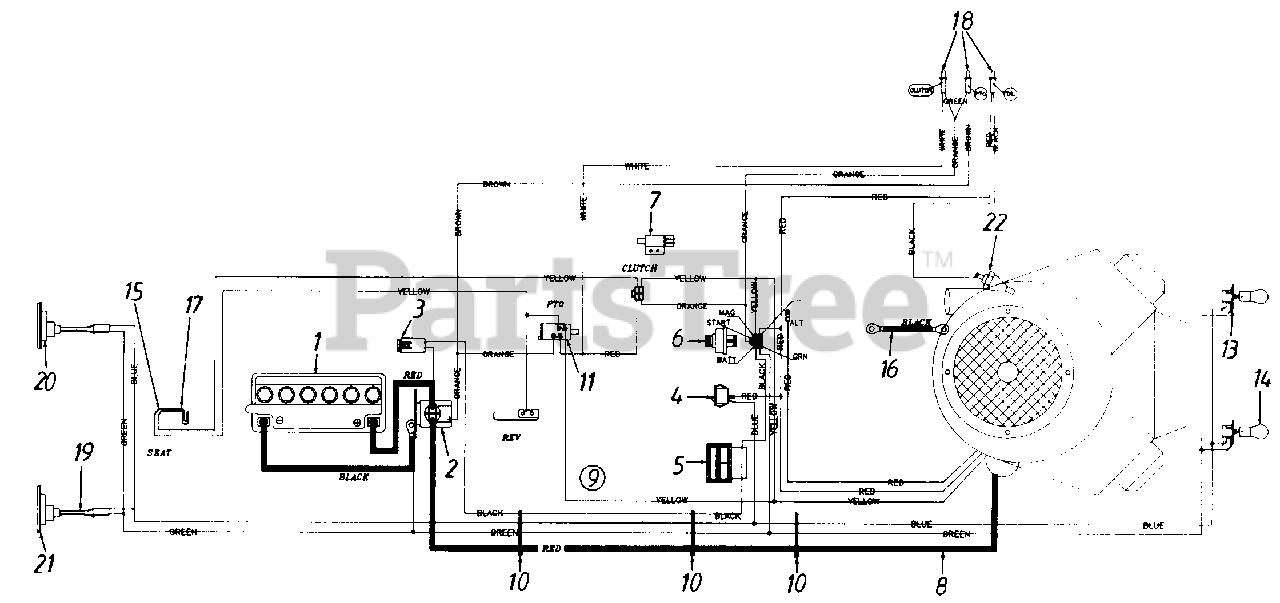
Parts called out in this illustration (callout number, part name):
1	Battery
2	Solenoid
3	Fuse 7.5 Amps
4	Light Switch
5	Ammeter
6	Ignition Switch
7	Safety Switch (Clutch)
8	Electric Wire 30" Lg.
9	Wire Harness
11	Safety Switch (Deck)
13	Socket
14	Bulb (Headlight)
15	Safety Switch (Seat)
16	Ground Wire 7.5" Lg.
17	Safety Switch (Seat)
18	Bulb
19	Taillight Harness
20	Taillight Ass'y.
21	Taillight Bulb
22	Oil Pressure Switch
